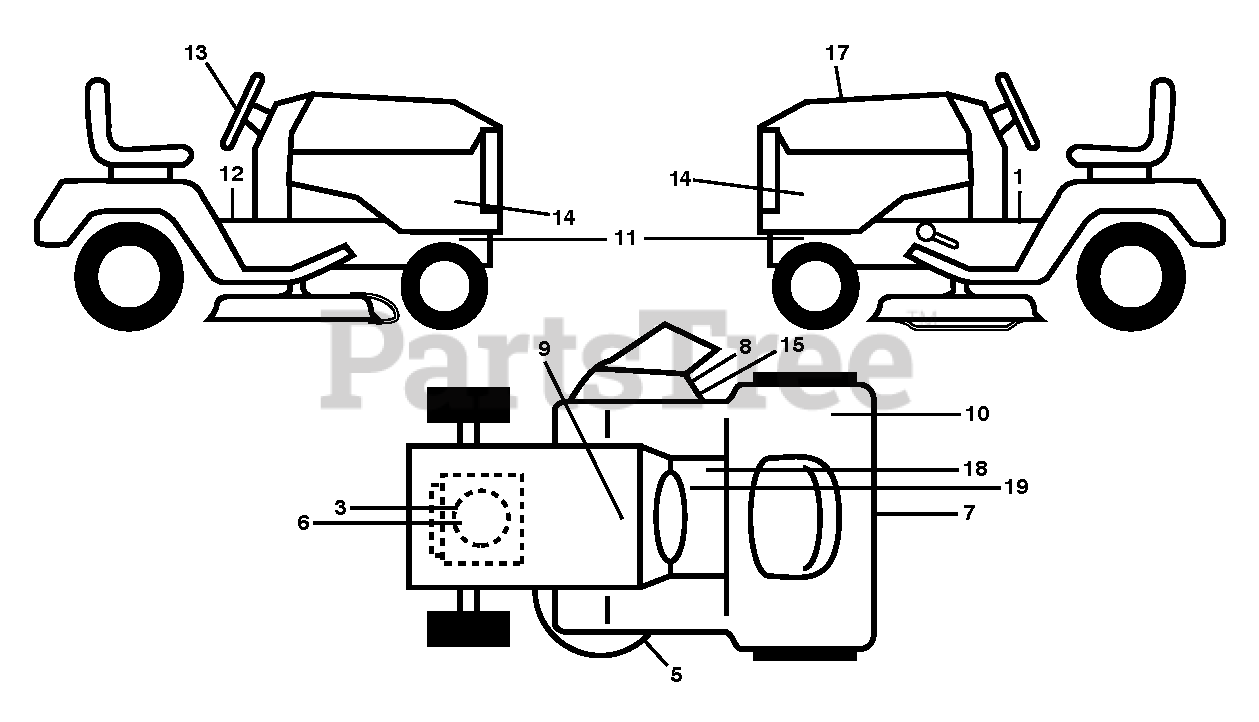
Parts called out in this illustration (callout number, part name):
5	DECAL.MOWER.SCH.48/54
8	DECAL.INTERNATIONL.CUTFINGER
9	DECAL BTRY SYMBOLS
10	DECAL.FENDER
15	DECAL, DEFLECT WARNING
19	DECAL PARK BRAKE
